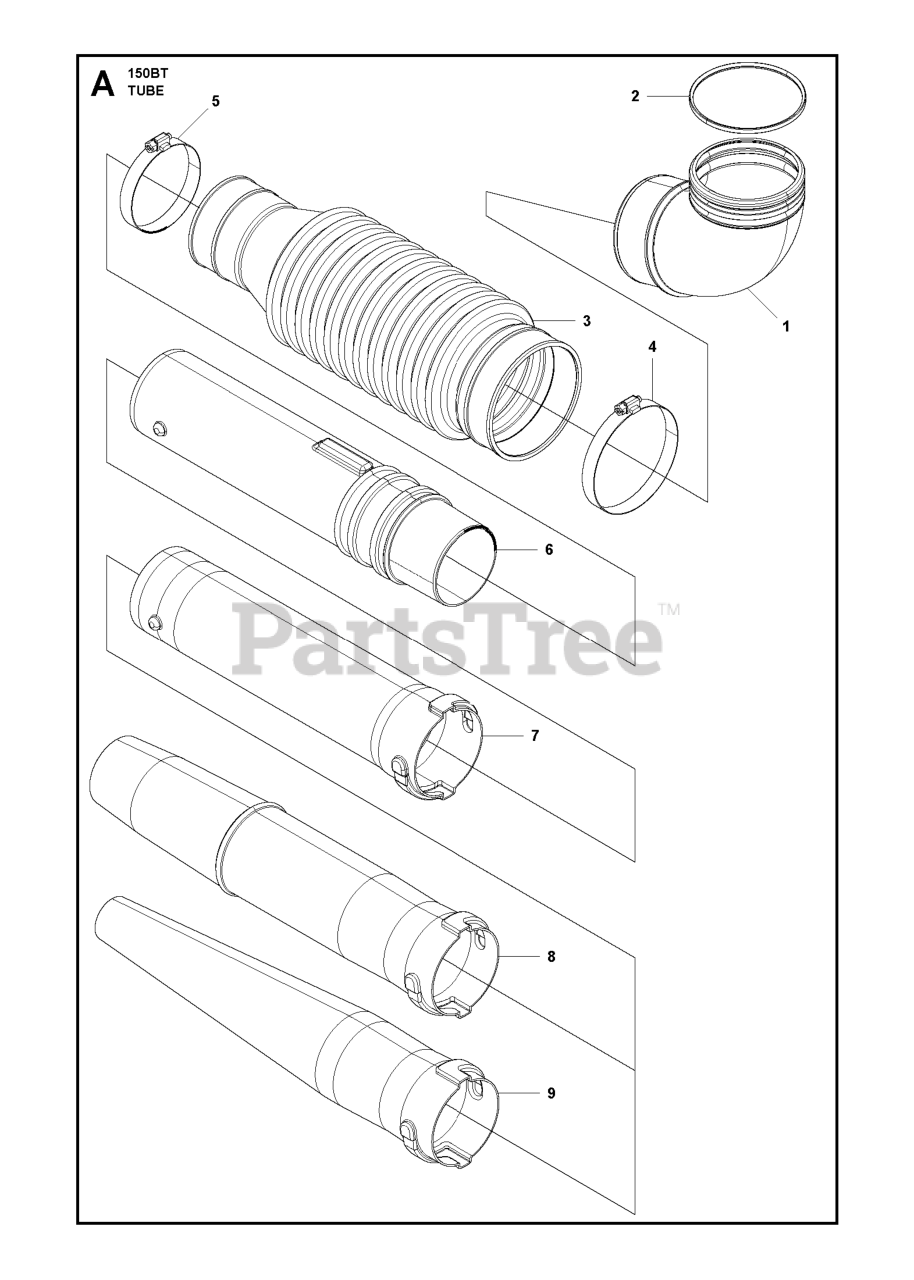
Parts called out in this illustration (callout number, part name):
3	PIPE FLEX T403051110
4	CLAMP(F115)
6	TUBE SWIVEL GREY
7	TUBE STRAIGHT GRAY
